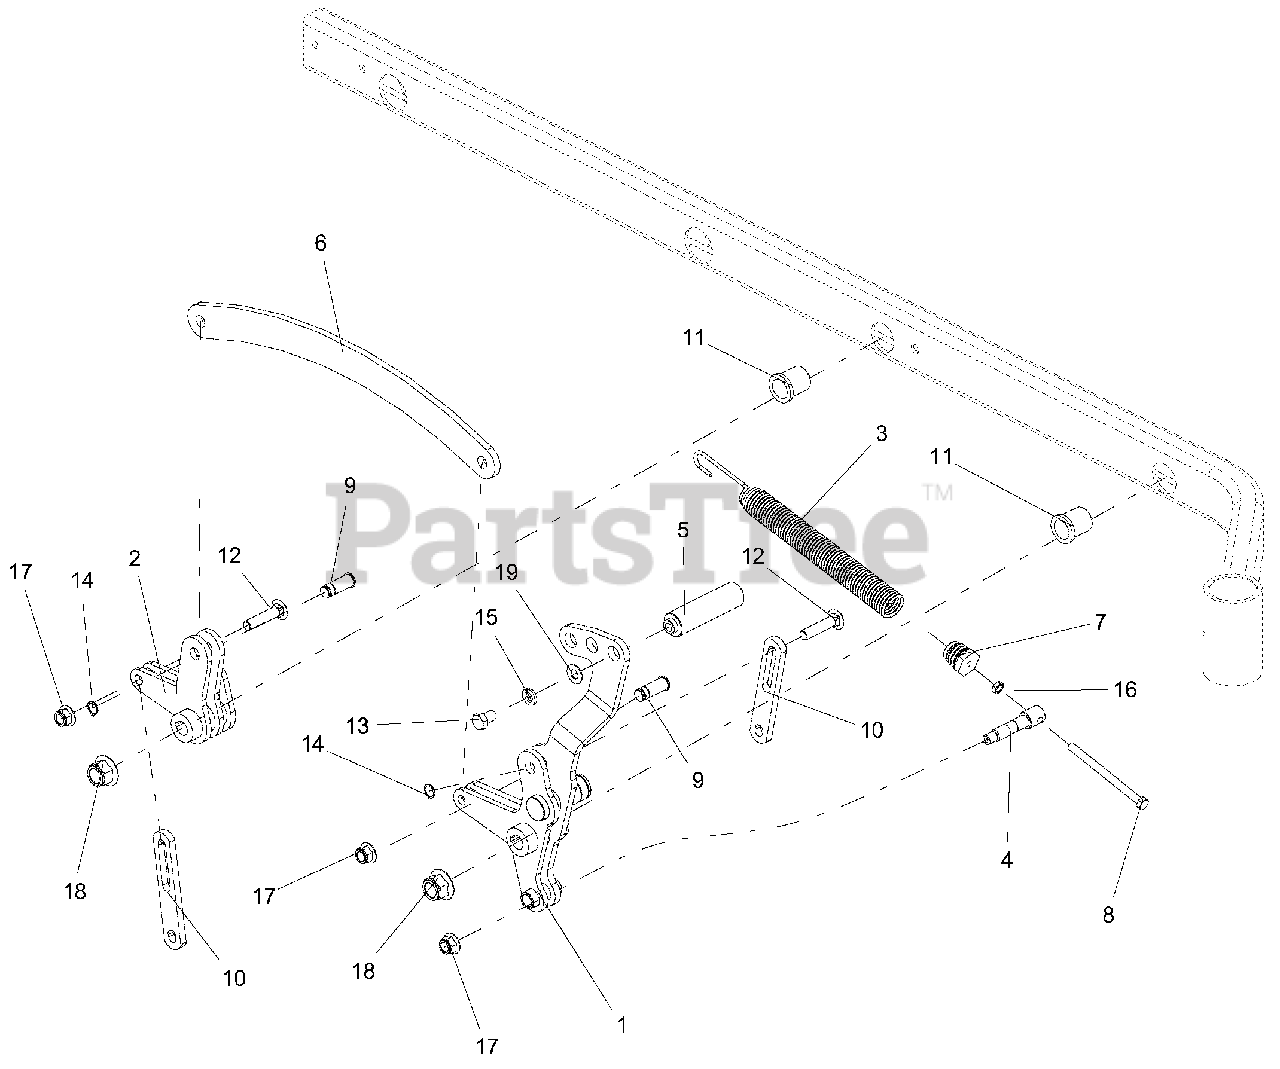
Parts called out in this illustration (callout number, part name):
1	WLDMT, PT400 FRONT RH DECK LIFT ARM-BLACK
2	WLDMT, PT400 REAR RH DECK LIFT ARM-BLACK
3	SPRG, DECK LIFT
4	TRUNION, SPRG
5	PEDAL, LIFT
6	LIFT, LINK - BLACK
7	PLUG, SPRG
8	BLT-HEX .38-16X5.00 GR5 YWZC
9	PIN, CLEVIS .625 SNAP RING
10	LINK, DECK LIFT - LONG
11	BSHG-FLG 1.00X1.25X1.5X1.5
12	BLT-RDHDSQNK .50-13X2.25 G5Y
13	BLT-HEX .50-13X.75 GR5 YWZC
14	RG-RTNG-EXT .625x.050
15	WSHR-LK .50X.125 REG YWZC
16	NUT, JAM .375-16 YWZC
17	NUT-LK-NYL-FLG .50-13 YWZC
18	NUT-LK-NYL-FLG .75-10 YWZC
19	WSHR-FL-STL .505X1.00X.062 YWZC
